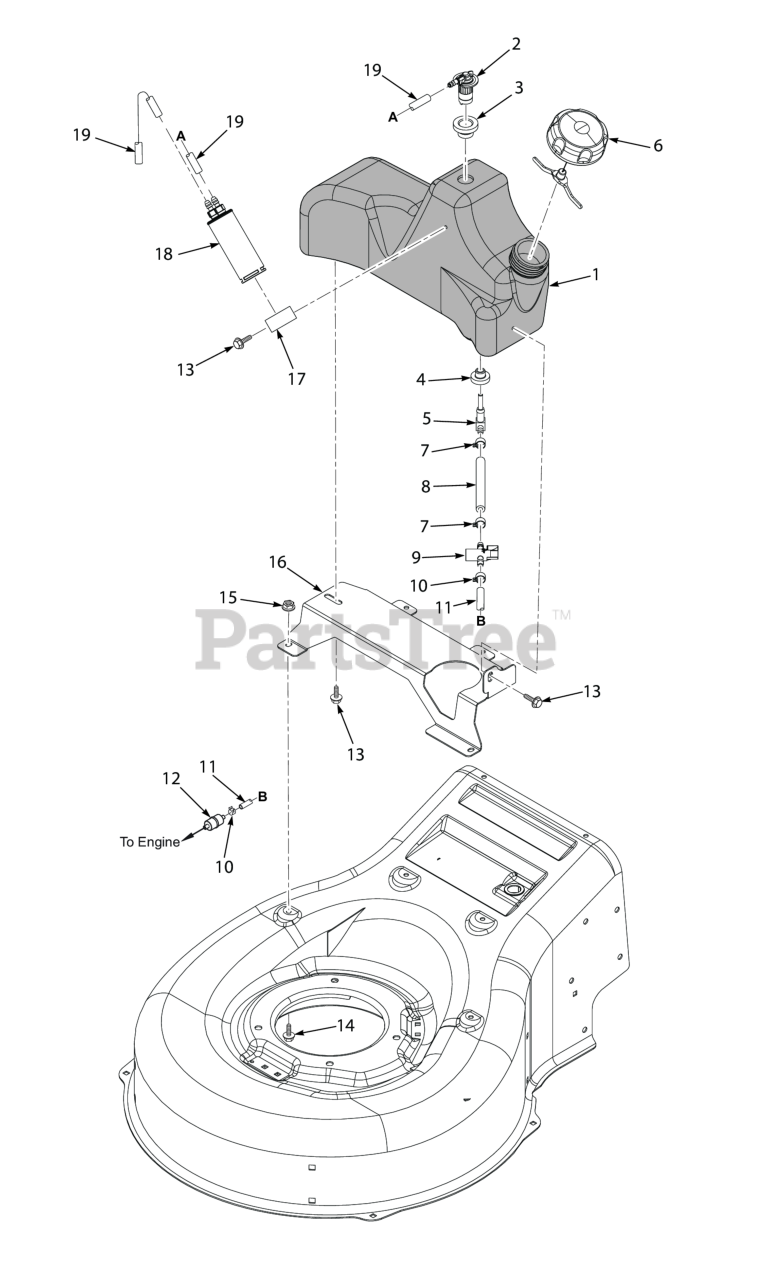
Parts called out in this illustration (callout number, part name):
1	Fuel Tank Assembly w/Decal (incl. #2, #3, #4, #5)
2	Valve
3	Grommet, Valve
4	Bushing, 0.56" Dia. Viton
5	Elbow, 90 Degree w/Screen
6	Cap, Fuel Tank
7	Clamp, Fuel Hose 1/4" Hose I.D.
8	Fuel Hose, 1/4" I.D. Non-Perm (791DFI Fuel Return) - Order by Inch
9	Valve, Fuel Shutoff
10	Clamp
11	Fuel Hose
12	Fuel Filter
13	CAP SCREW, 1/4-20 X 1/2" SERRATED FLANGE HEX
14	Bolt, Carriage 1/4-20 x 1/2"
15	Nut, Flanged Elastic Stop 1/4-20
16	Bracket, Fuel Tank Mounting
17	Clamp, 1-1/2" Cable
18	Canister, Carbon 1.28 Gal.
19	Hose, Vapor Recovery 3/16" (order by inch)
